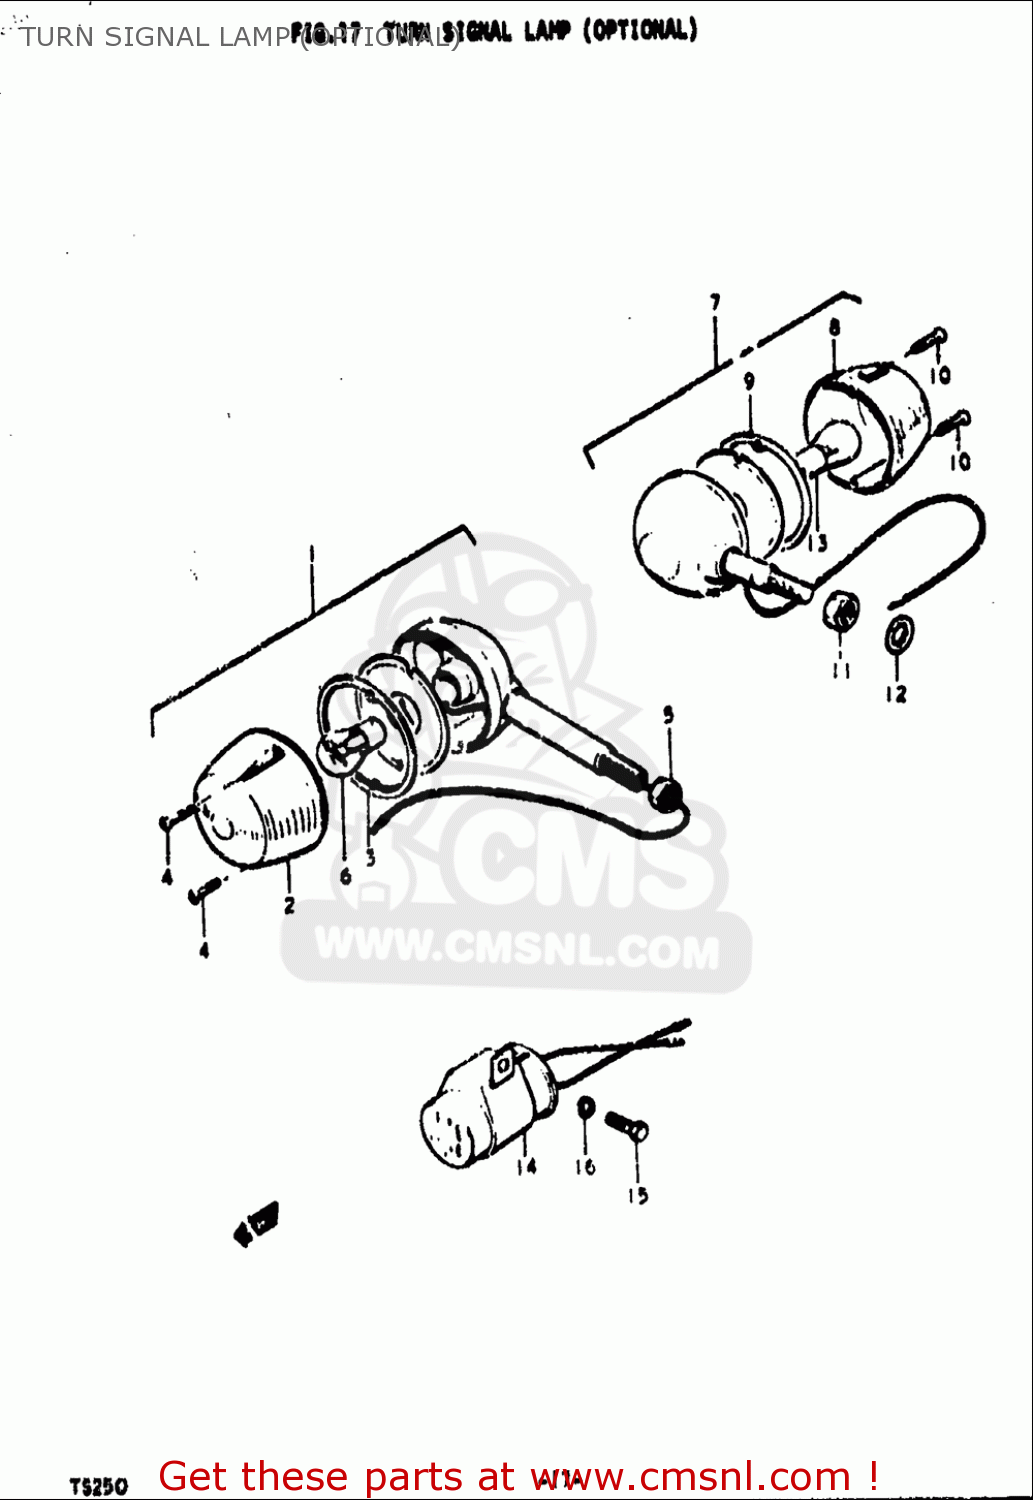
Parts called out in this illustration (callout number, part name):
2	LENS,TURNSIGNAL
3	GASKET,TURNSIGNAL LENS (NAS)
4	SCREW
5	NUT
6	BULB(6V17W,STANLEY,A4513A)
7	LAMP ASSY,RR TURNSIGNAL
8	LENS,RR TURNSIGNAL LAMP
9	GASKET,TURNSIGNAL LENS (NAS)
10	SCREW
11	NUT
13	BULB(6V17W,STANLEY,A4513A)
14	RELAY ASSY,TURNSIGNAL
15	BOLT
16	WASHER,LOCK
